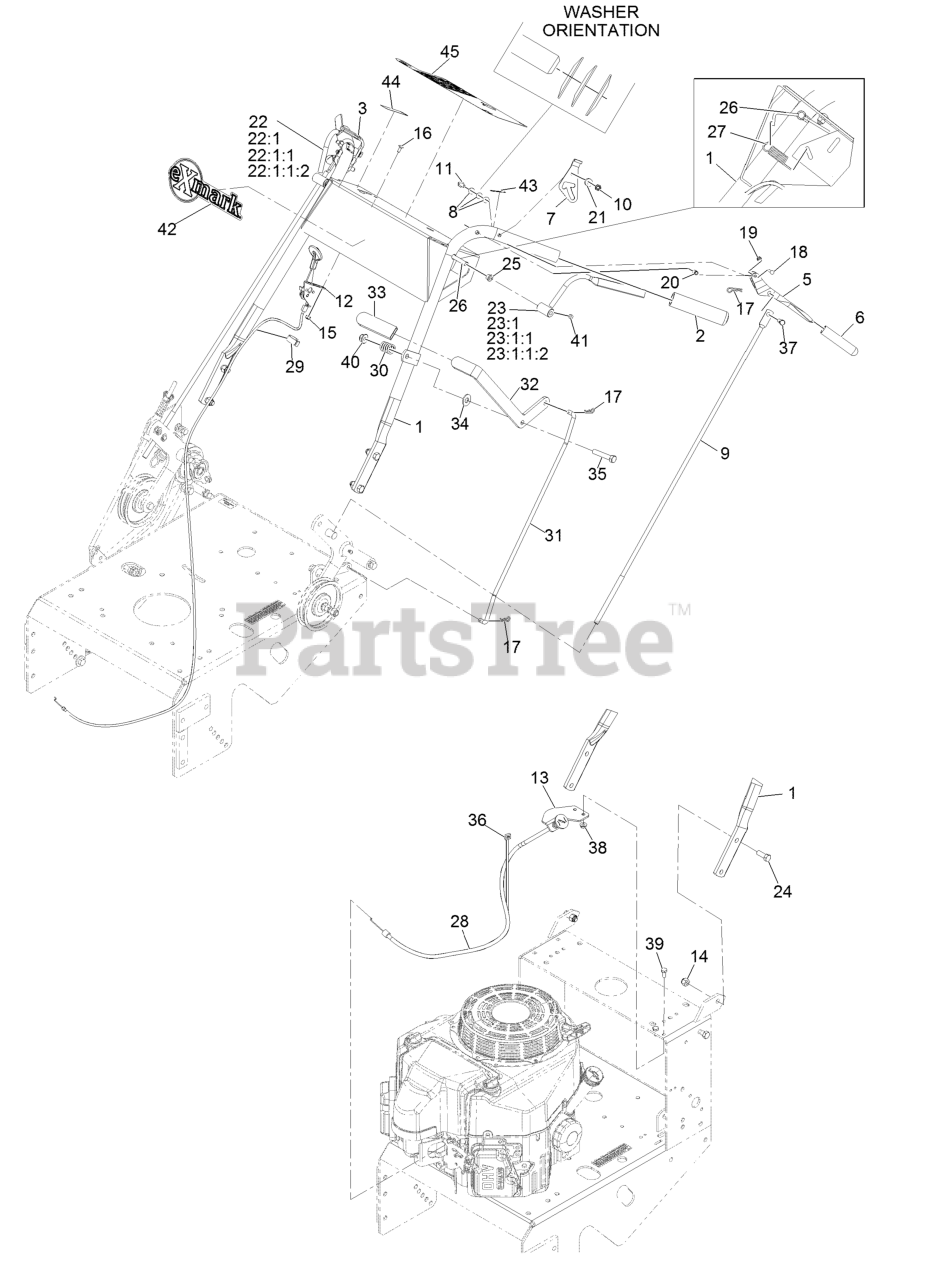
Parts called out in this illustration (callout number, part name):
1	Wld,Handle Metro
1	Kit, Handle W/Decals
2	Grip-Foam
3	Latch-LH Thumb,W/Grip
5	Drive Lever ASM
6	Grip-Lever, Drive
7	Latch-RH Thumb,W/Grip
8	Washer-Spring Disc 1/4
9	Linkage-Wheel, Drive
10	Nut-Nyloc 1/4-20
11	Screw-HH 1/4-20 X 2 1/4
12	Control, Throttle
13	Bracket-Cable, Choke
14	Nut-Nyloc 3/8-16
15	Nut-Nyloc #10-24
16	Bolt-Carriage #10-24 X 1/2
17	Hairpin-Cotter
18	Pin-Lever, Drive
19	Nut-Push
20	Pin-Roll
22:1	Lever
22:1:1	ASM,Hub/Setscrew
22:1:1:2	Setscrew-5/16-24 X 5/16
23:1	Lever
23:1:1	ASM,Hub/Setscrew
23:1:1:2	Setscrew-5/16-24 X 5/16
24	Screw-HH 3/8-16 X 1
25	Bushing-Nylon
26	Rod Weldmt, Opc
27	Spring-Extension
28	Cable-Choke
29	Clip-Cable
30	Spring-Compression
31	Linkage-Blade, Upper
32	Lever ASM
33	Grip-Lever
34	Washer-3/8 Std
35	Screw-HH 3/8-16 X 2
36	Tie-Cable 7 15/16 (Large)
37	Pin-Clevis
38	Nut-Whizlock 1/4-20
39	Screw-HH 1/4-20 X 5/8
40	Nut-Nyloc 3/8-16 Flg
41	Setscrew-5/16-24 X 5/16
42	Decal, Exmark Logo
43	Decal-Neutral Brake
44	Decal-Throttle
45	Decal-Console
